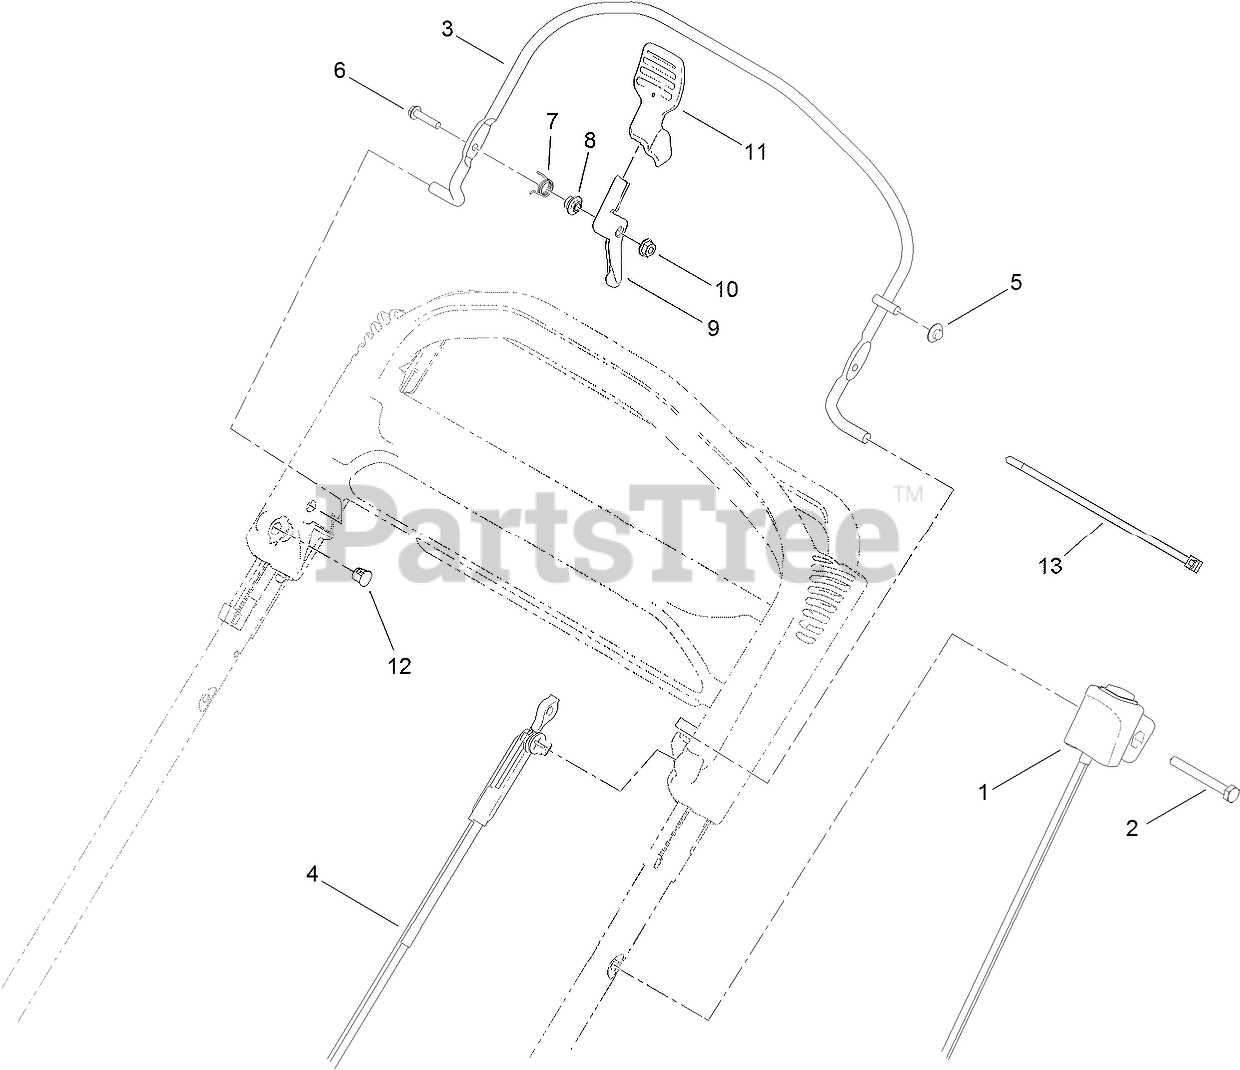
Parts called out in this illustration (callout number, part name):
1	SWITCH HOUSING ASM
2	SCREW-HH
3	BAIL-BRAKE
4	CABLE-BRAKE
5	NUT-SPEED
6	SCREW-HWH
7	SPRING-TORSION
8	SPACER
9	LEVER
10	NUT-LOCK, FLANGE
12	Plug-Dome
13	TIE-CABLE
